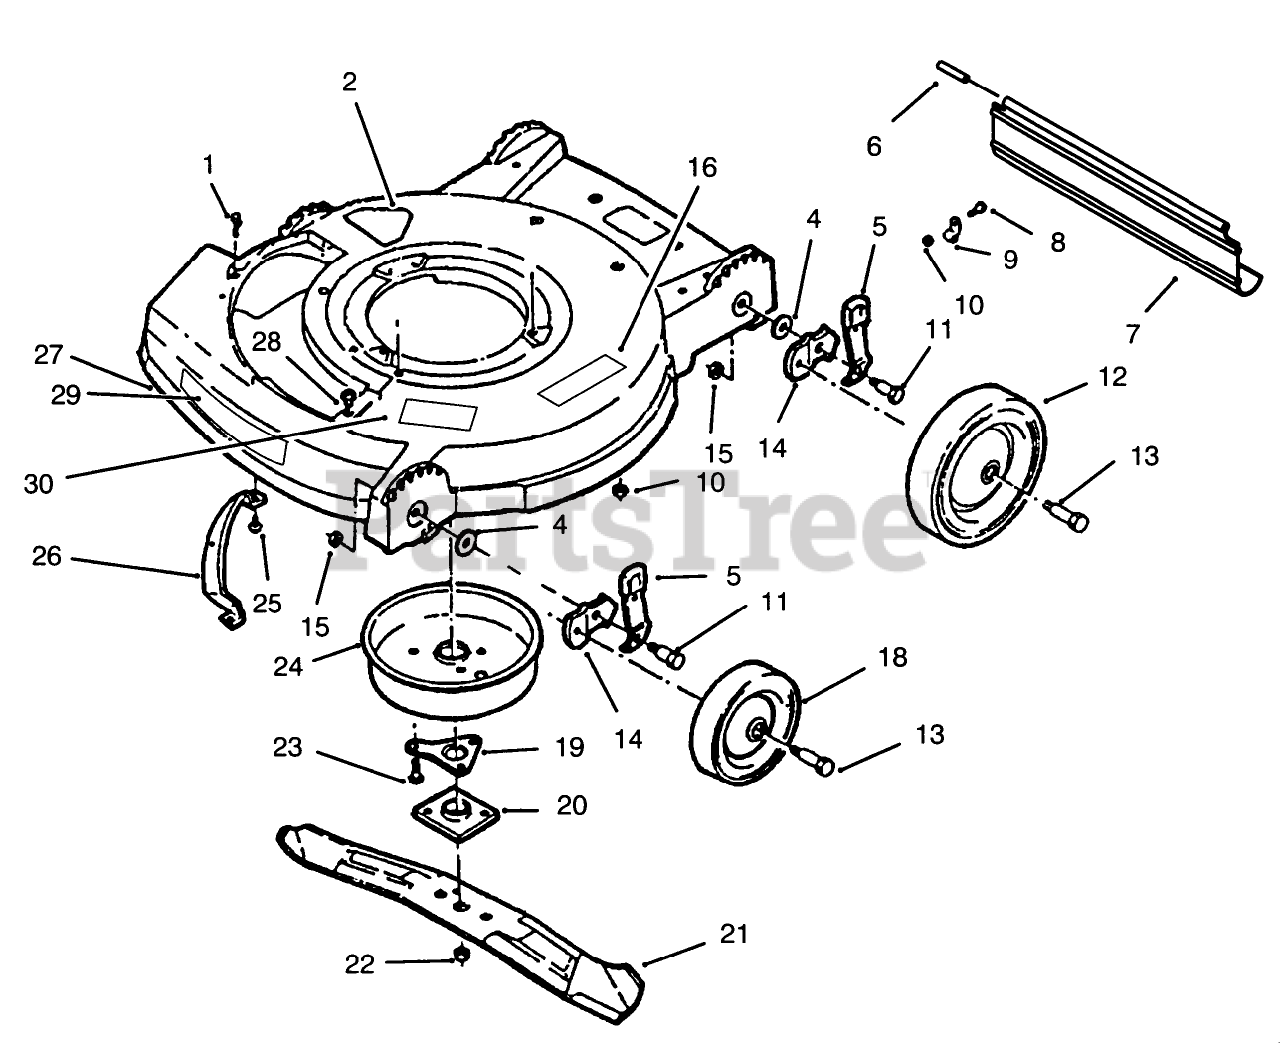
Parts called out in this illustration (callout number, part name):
1	SCREW-SEMS
2	DECAL-DANGER
5	SPRING ARM ASM
7	SHIELD - TRAILING
9	CLAMP ROD KMC
10	NUT-LOCK, NI
12	8" WHEEL/TIRE ASM-GREY
13	BOLT-SHOULDER
15	NUT-LOCK, NI
16	DECAL-WARNING
19	SUPPORT F
20	PLATE AND COLLAR ASM
22	NUT-BLADE
24	MUFFLER COVER F
25	SCREW-HWH
26	BAR-TOE
